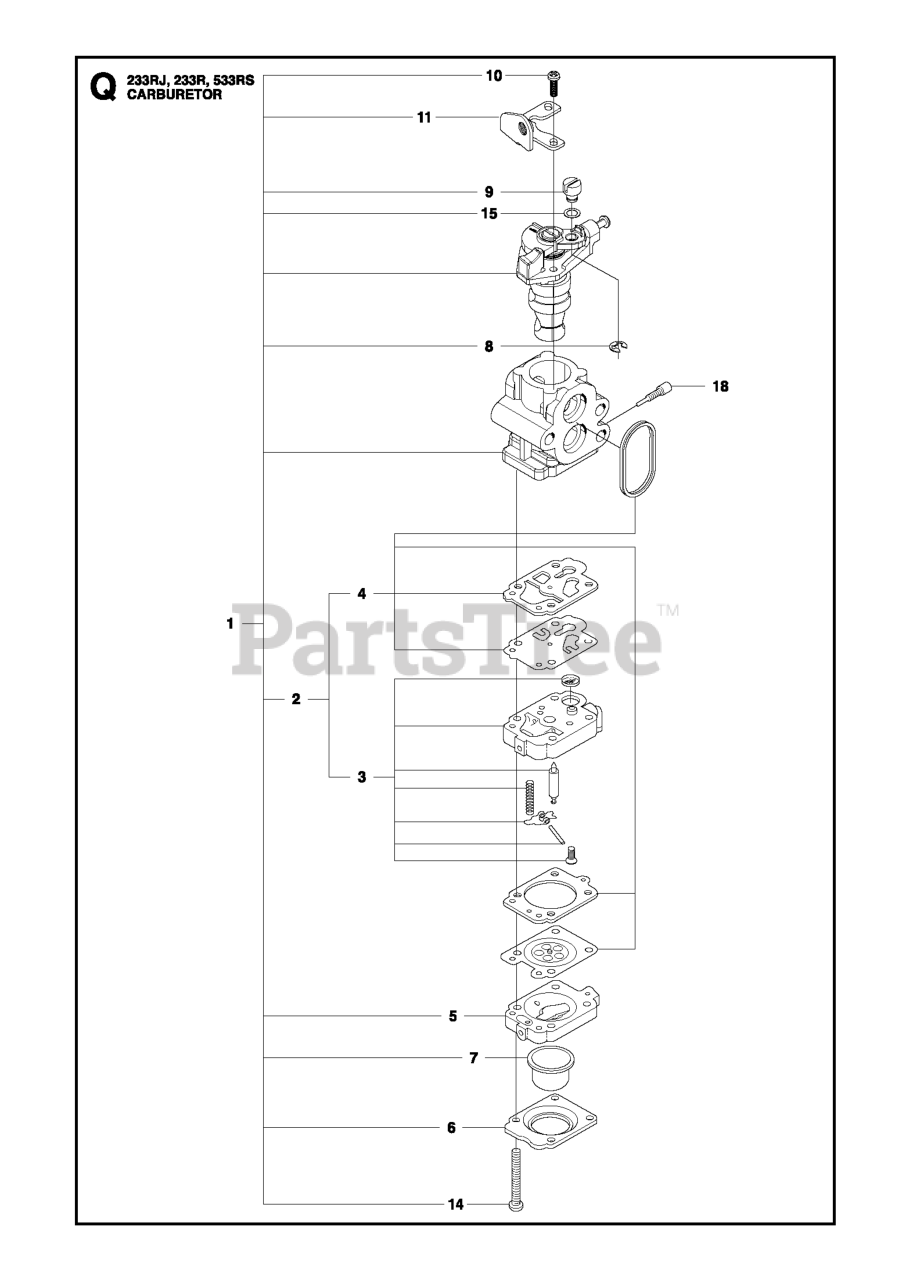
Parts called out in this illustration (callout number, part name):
2	REBUILD KIT
3	CARBURETOR BODY
4	GASKET KIT
